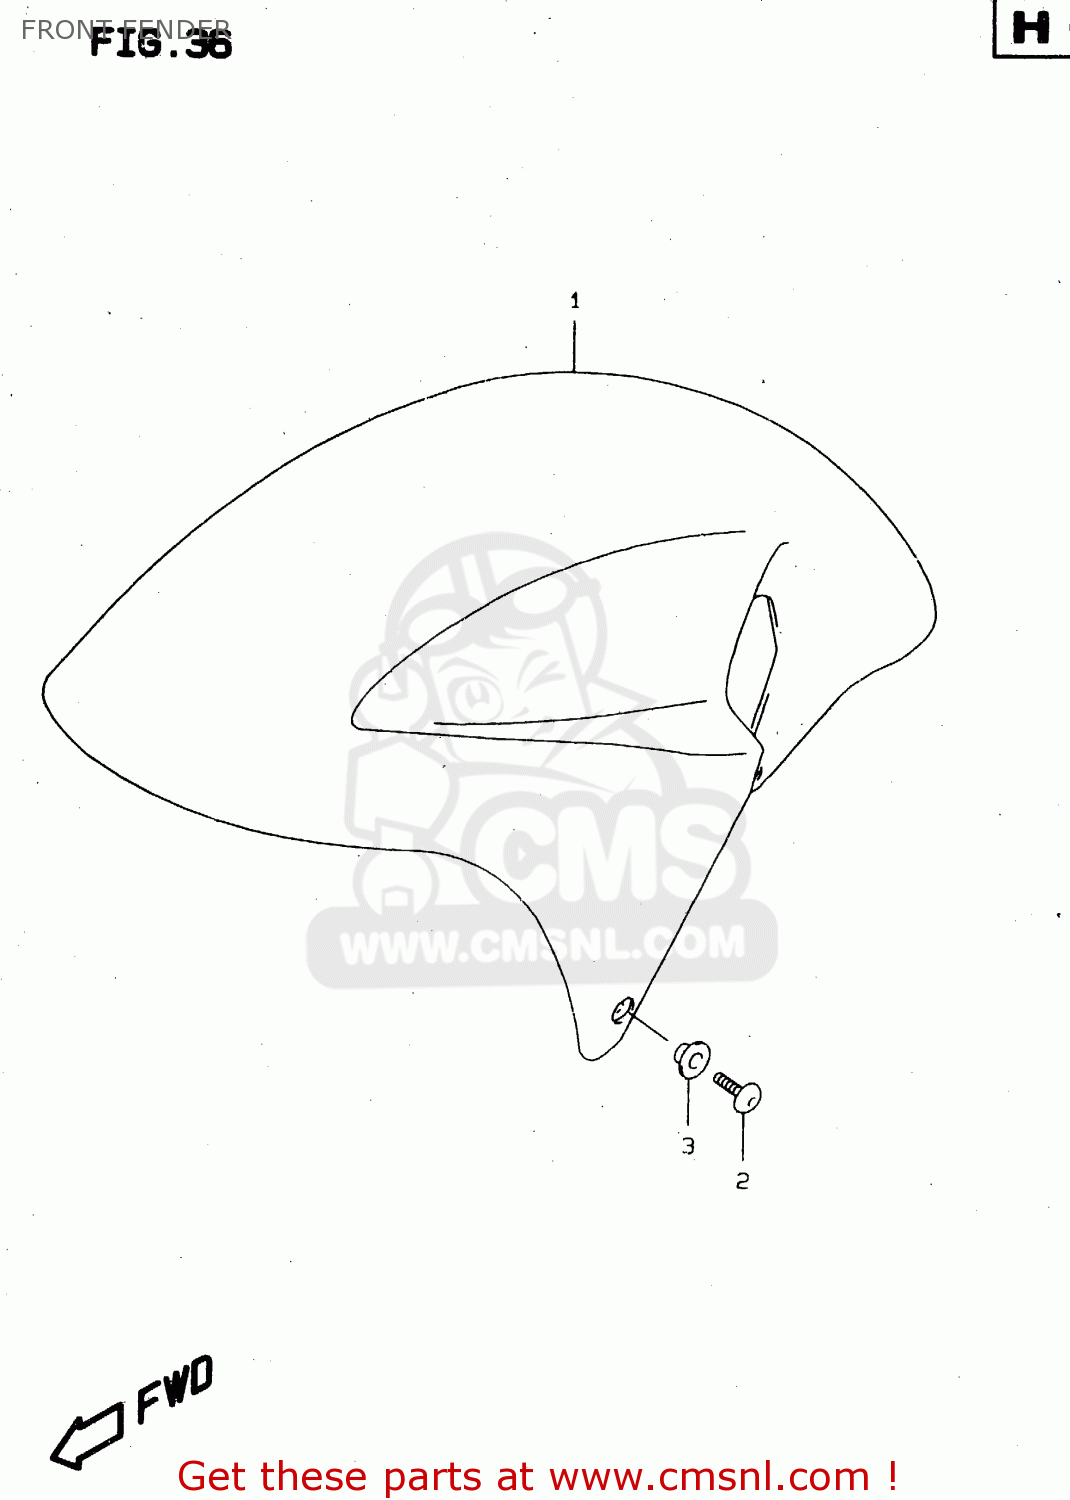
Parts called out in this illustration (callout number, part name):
1	FENDER,FR
2	SCREW(6X16)
3	WASHER(6.3X16X1.5)
